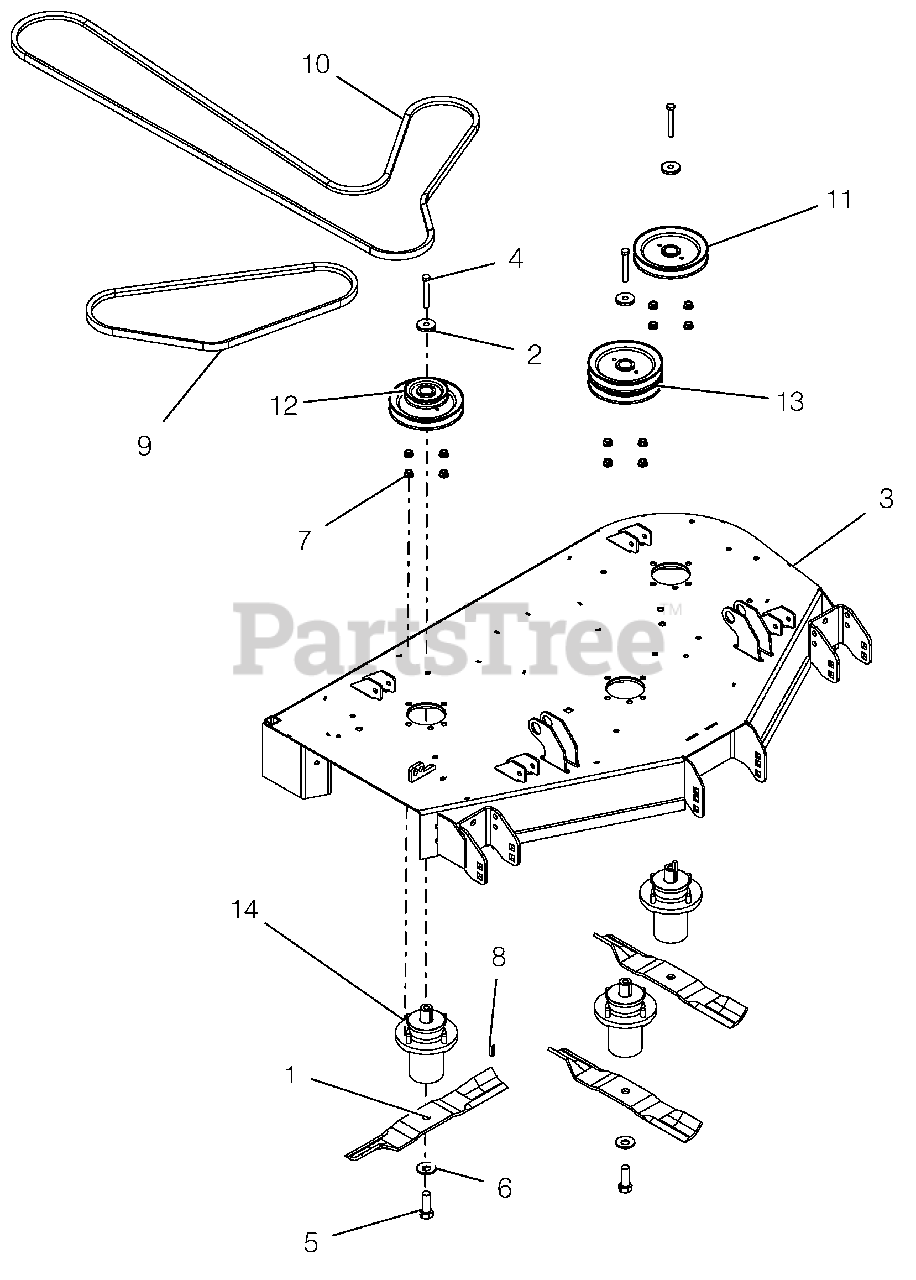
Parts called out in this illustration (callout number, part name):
1	BLADE, 16.19" MOWER (HI-LIFT)
2	RETAINER, SHEAVE
3	KIT,DECK-44" W/DECALS -GRAVELY
4	BLT-HEX .38-16X2.75 GR8 YWZC
5	BLT-HEX .62-18X1.75 GR8 YWZC
6	WSHR-BLVL .669X1.535X.138
7	NUT-LK-CTR-FLG .38-16 YWZC
8	KEY, SQ .25X.25X1.00 RC 40-50
9	V-BELT, B-COGGED
10	V-BELT, HB RAW EDGE EPDM
11	PULLEY, SINGLE-1"ID X 6" OD
12	PULLEY, DOUBLE-1"IDX3.50"&6.0
13	PULLEY, DOUBLE
14	ASM, MAINT FREE SPINDLE ALUM
